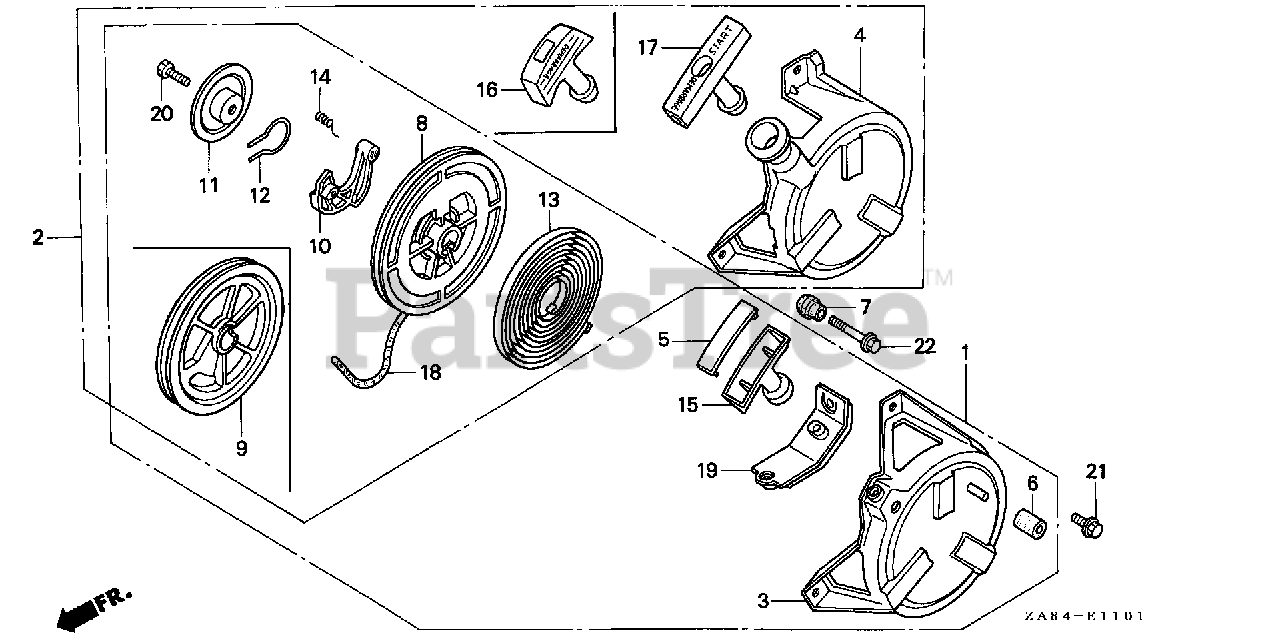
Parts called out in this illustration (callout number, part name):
2	STARTER ASSY., RECOIL
4	CASE, RECOIL STARTER
7	STOPPER ASSY., BUMPER
8	REEL, RECOIL STARTER
10	RATCHET, STARTER
11	PLATE, FRICTION
12	SPRING, FRICTION
13	SPRING, RECOIL STARTER
14	SPRING, RETURN
16	KNOB, RECOIL STARTER
17	KNOB, STARTER
18	ROPE, RECOIL STARTER (#4X55")
18	ROPE (#4X55")
20	BOLT, HEX. (6X20)
21	BOLT-WASHER (6X10)
22	BOLT, FLANGE (6X32)
